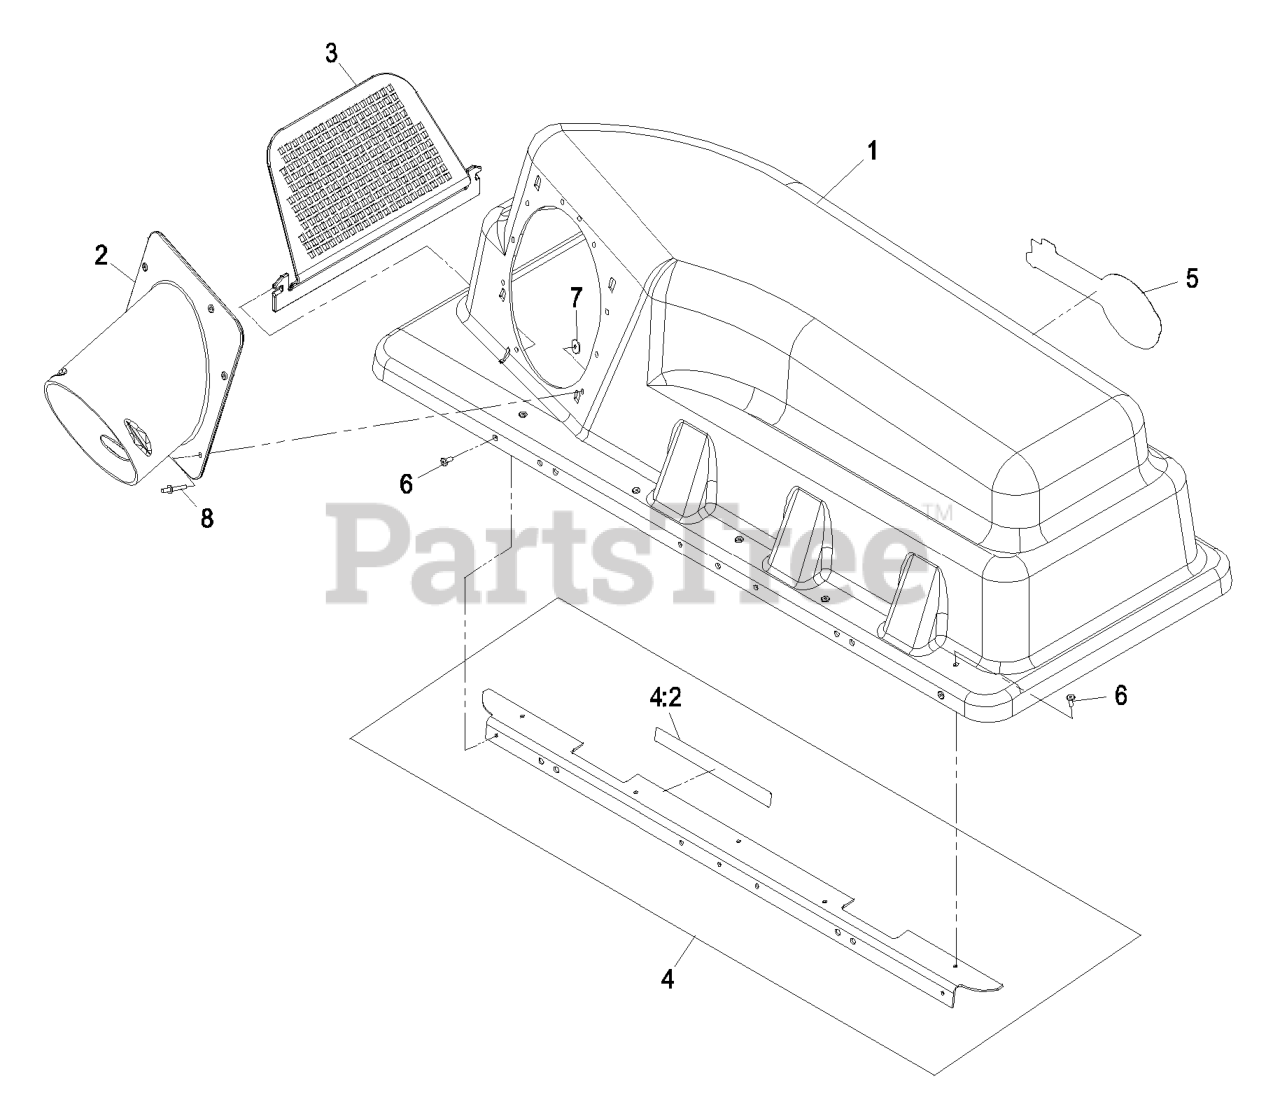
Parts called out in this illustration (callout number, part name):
1	HOOD,BAGGER
2	TUBE,UPPER
3	SCREEN-BAGGER
4	ASM,STIFFENER W/DECAL
4:2	DECAL-CAUTION, BAGGER
5	DECAL, EXMARK LOGO
6	RIVET-BLIND
7	WASHER-FLAT
8	RIVET-POP
